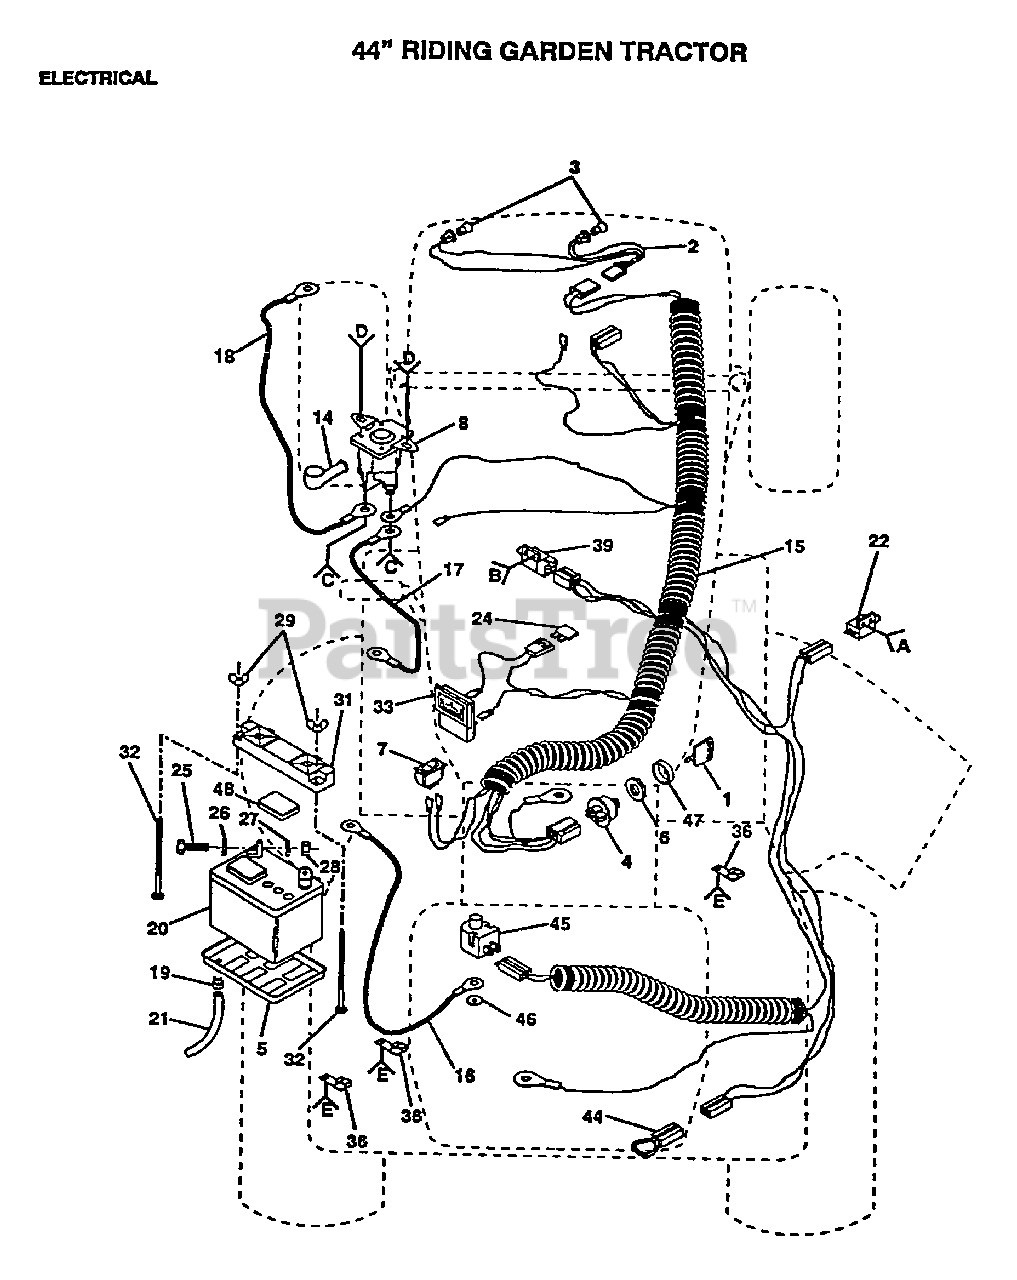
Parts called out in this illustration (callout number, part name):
1	KEY
2	HARNESS T
5	"TRAY T, BATTERY"
7	SWITCH LT
10	NUT
11	BOLT
13	NUT
15	HARNESS
16	"CABLE T, BATTERY"
17	CABLE LT
18	CABLE T
19	HOSE CLAMP T
22	SWITCH-INTER. GT
23	SCREW
24	FUSE HYT
25	BOLT LT
26	WASHER
27	LOCKWASHER
32	BOLT
36	CLIPT
39	SWITCH INTERLOCKT
42	SCREW
43	"NUT,KEPS"
45	SWITCH SEAT
46	LOCKWASHER
48	"CAP,BATTERY "
